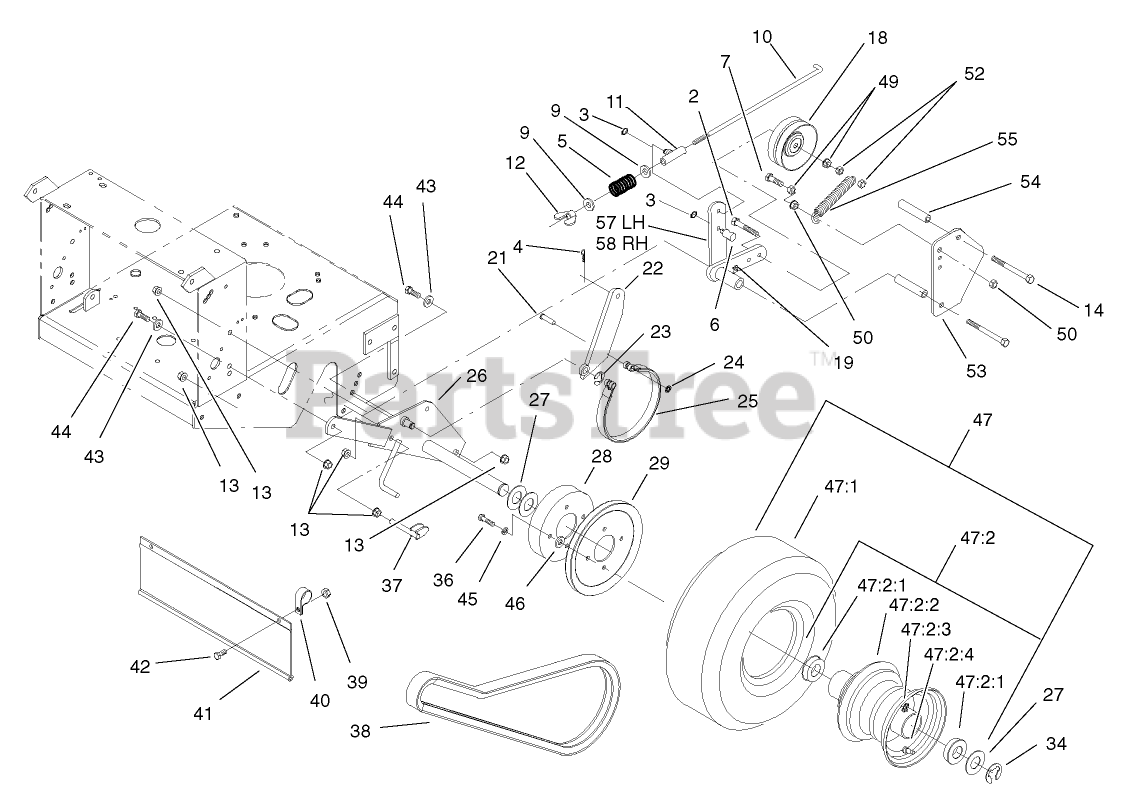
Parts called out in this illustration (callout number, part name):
2	SCREW-HH
3	RING-RETAINING
4	PIN-COTTER
5	SPRING-COMPRESSION
6	Swivel-Lever, Drive
7	SCREW-HH
9	WASHER-PLAIN
10	Linkage-Brake
11	SWIVEL-BRAKE
12	WINGNUT-NYLOCK
13	NUT-HHF, WHIZ
14	SCREW-HH
18	IDLER-WHEEL, DRIVE
19	FITTING-GREASE
21	PIN-CLEVIS
22	ARM-BRAKE
23	RING-RETAINING, EXTERNAL
24	NUT-PUSH
25	BAND-BRAKE
27	WASHER-SPACER
28	DRUM-BRAKE
29	SHEAVE-WHEEL, DRIVE
34	RING-SNAP
36	SCREW-HH
37	Scraper
38	Belt-Wheel, Drive
39	NUT-LOCK, NI
40	CLAMP-R
41	SHIELD-TRAILING
42	SCREW-HH
43	WASHER-BELLEVILLE
44	SCREW-HH
45	WASHER
46	WASHER-LOCK
47	WHEEL AND TIRE ASM
47:2	WHEEL AND HUB ASM
47:2:1	BEARING-FLANGED
47:2:2	Rim ASM
47:2:3	Fitting-Grease
47:2:4	Valve Stem and Cap
49	NUT-HHF, WHIZ
50	NUT-HF
52	NUT-LOCK, NI
53	Shield-Wheel, Drive
54	Spacer-Shield, Lower
55	SPRING-EXTENSION
57	Arm-Idler, LH
58	Arm-Idler, RH
